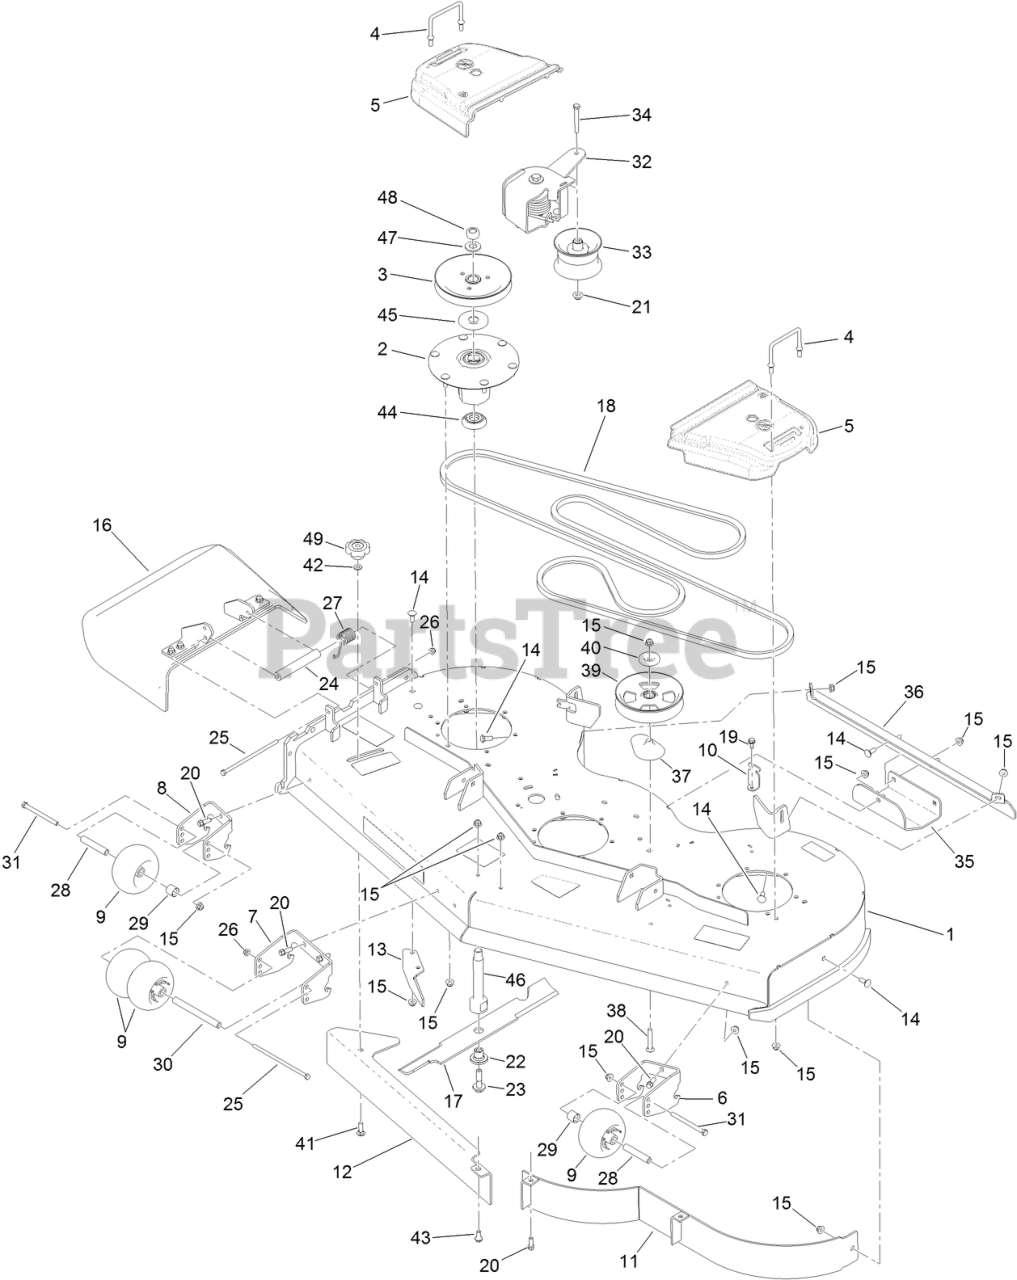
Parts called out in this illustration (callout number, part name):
1	60 DECK ASM
2	SPINDLE ASM
3	SHEAVE-DRIVE, BLADE
4	WIREFORM-COVER
5	COVER-BELT, LH
6	BRACKET-WHEEL, LH
7	BRACKET-WHEEL, CENTER
8	BRACKET-WHEEL, RH
9	ROLLER-SCALP, ANTI
10	BRACKET-COVER
11	BAFFLE ASM
12	PLATE-BAFFLE, FORMED [RED]
13	BAFFLE-DISCHARGE
14	BOLT-CARR
15	NUT-HF, NI
16	DEFLECTOR ASM
18	BELT-V
19	SCREW-HWHTF
21	NUT-FLANGE, NI
22	BUSHING-HEX
23	SCREW-SEMS
24	SPACER
25	SCREW-HH
26	NUT-HF, NI
27	SPRING-TORSION
28	TUBE-SPANNER
29	SPACER-AXLE, REAR
30	SPACER-WHEEL
31	SCREW-HH
32	GS TORSION IDLER ASM II
33	PULLEY-IDLER
34	SCREW-HH
36	BRACKET-SKID
37	SPACER-PULLEY
38	SCREW-CARR
39	PULLEY-IDLER, FLAT
40	SHIELD-DUST
41	BOLT-CARR
42	WASHER-HARDENED
43	BOLT-SHOULDER
44	GUARD-BOTTOM
45	GUARD-BEARING, TOP
46	SHAFT-SPINDLE
47	WASHER
48	NUT-HEX
